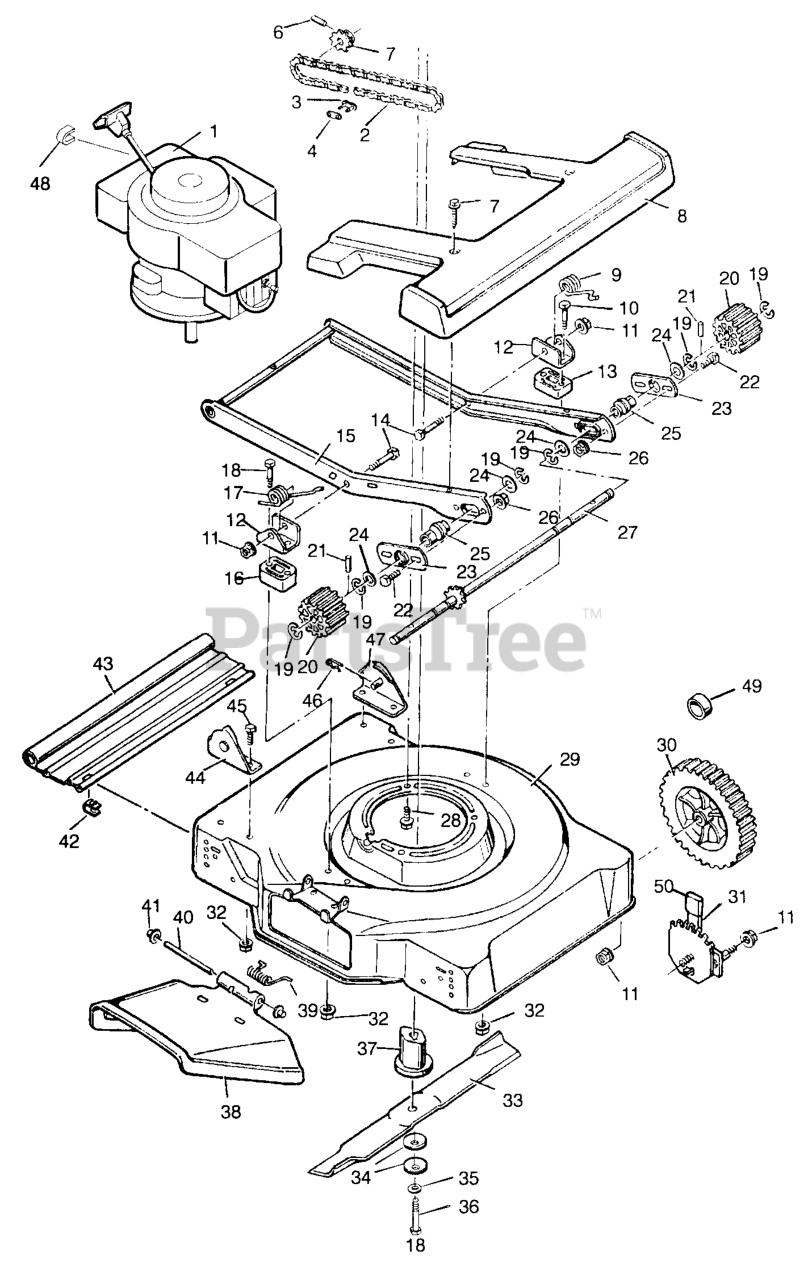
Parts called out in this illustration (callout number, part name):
1	Engine *
3	Master Link
5	Sprocket, Drive
6	Pin, Spring
7	Screw, Tapping
8	Guard, Pinion
9	Spring, Left Torsion
10	Bolt, Hex
11	Locknut, Flange
12	Bracket, Drive Arm
13	Spacer, Left
14	Bolt, Hex
15	Drive Arm Assembly
16	Spacer, Right
17	Spring, Right Torsion
18	Bolt, Hex
19	Retainer Ring
20	Drive Pinion
21	Spring Pin
22	Bolt, Hex
23	Retainer, Bearing
25	Bearing
26	Locknut, Flange
27	Drive Shaft & Sprocket
28	Bolt, Engine
29	Housing
30	Wheel, Plastic
31	Height Adjuster
32	Locknut, Flange
34	Washer, Belleville
37	Blade Adapter
38	Chute Deflector
39	Spring, Torsion
40	Pin, Pivot
41	Push On Cap
42	Retainer
43	Deflector, Rear
44	Bracket, Right Handle
46	Pin, Hair
47	Bracket, Left Handle
48	Stop, Rope
49	Hub Cap
